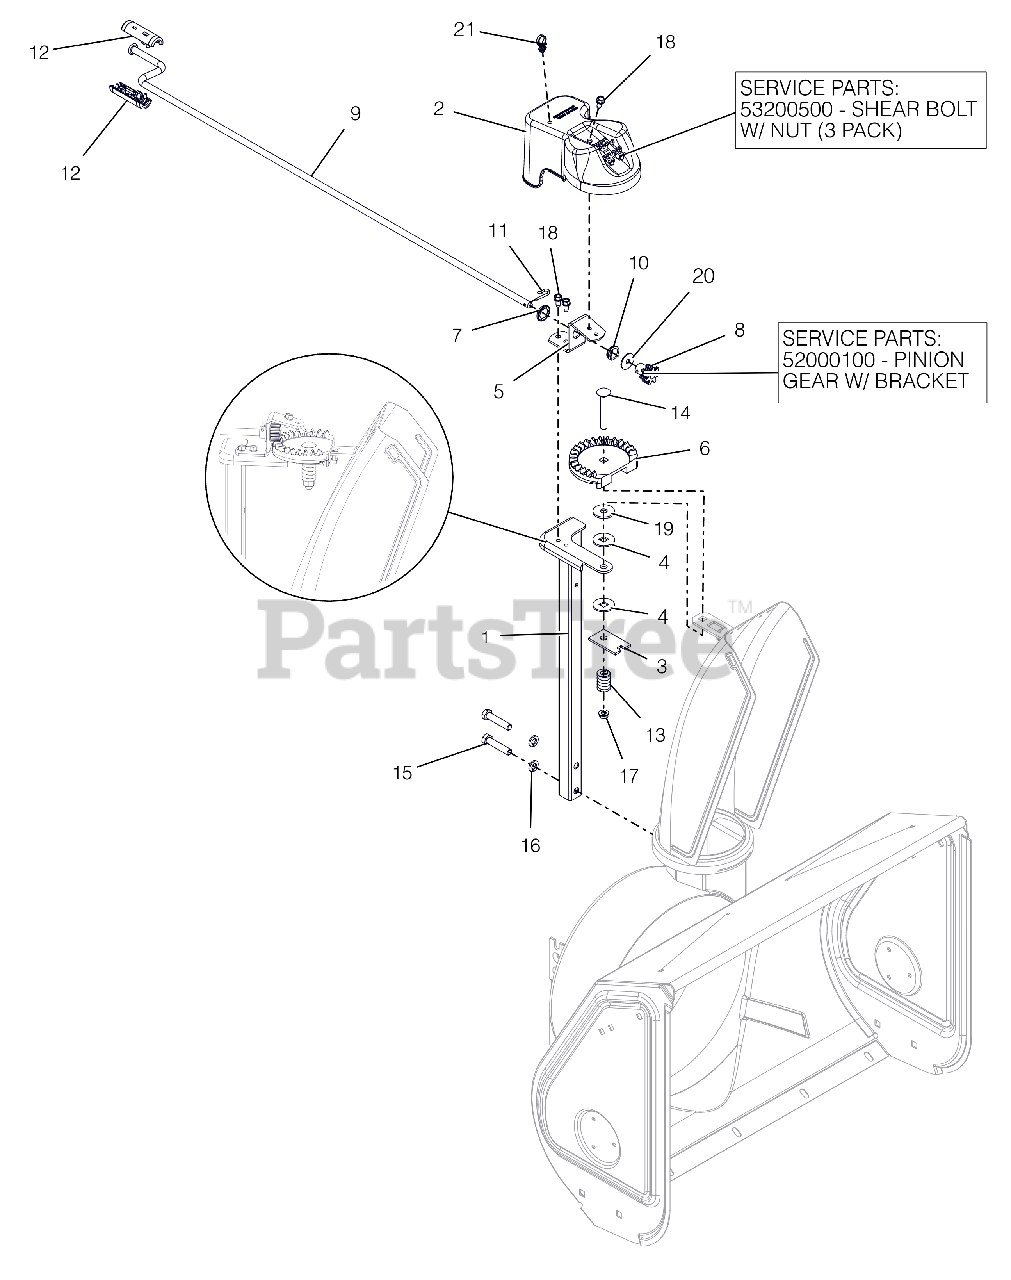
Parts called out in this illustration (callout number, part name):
1	CHUTE PEDESTAL, TALL COMPACT
2	GEAR COVER,SM SHEAR BOLT
2	SHEAR BOLT WITH NUT
3	PLATE, FRICTION
4	FRICTION WASHER
5	BRACKET, PINION GEAR
6	CHUTE GEAR
7	PUSHNUT .625
8	PINION GEAR - CHUTE
8	PINION GEAR W/BRACKET
9	ROD, CHUTE CRANK, COMP&SNOTEK
10	BUSHING, POLYLINER-.63 SNAPIN
11	PIN, SPRING CLIP
12	KNOB,CRANK-SNAP COMPACT-GRAY
13	SG-COMP .187X.56X1.62
14	@BLT-RDHDSQNK .38-16X2.50 G5YZ
15	@BLT-HEX .38-16X1.75 GR5 YWZC
16	@WSHR-LK .38X.094 REG YWZC
17	@NUT-LK-TOP-FLG .25-20 YWZC
18	SCR-TAP .25-20X.50 HWH TR YWZ
19	@WSHR-FL-STL .406X1.25X.10 ZC
20	WSHR-FL-STL .281X1.000X.063
21	CLIP, CABLE GUIDE
